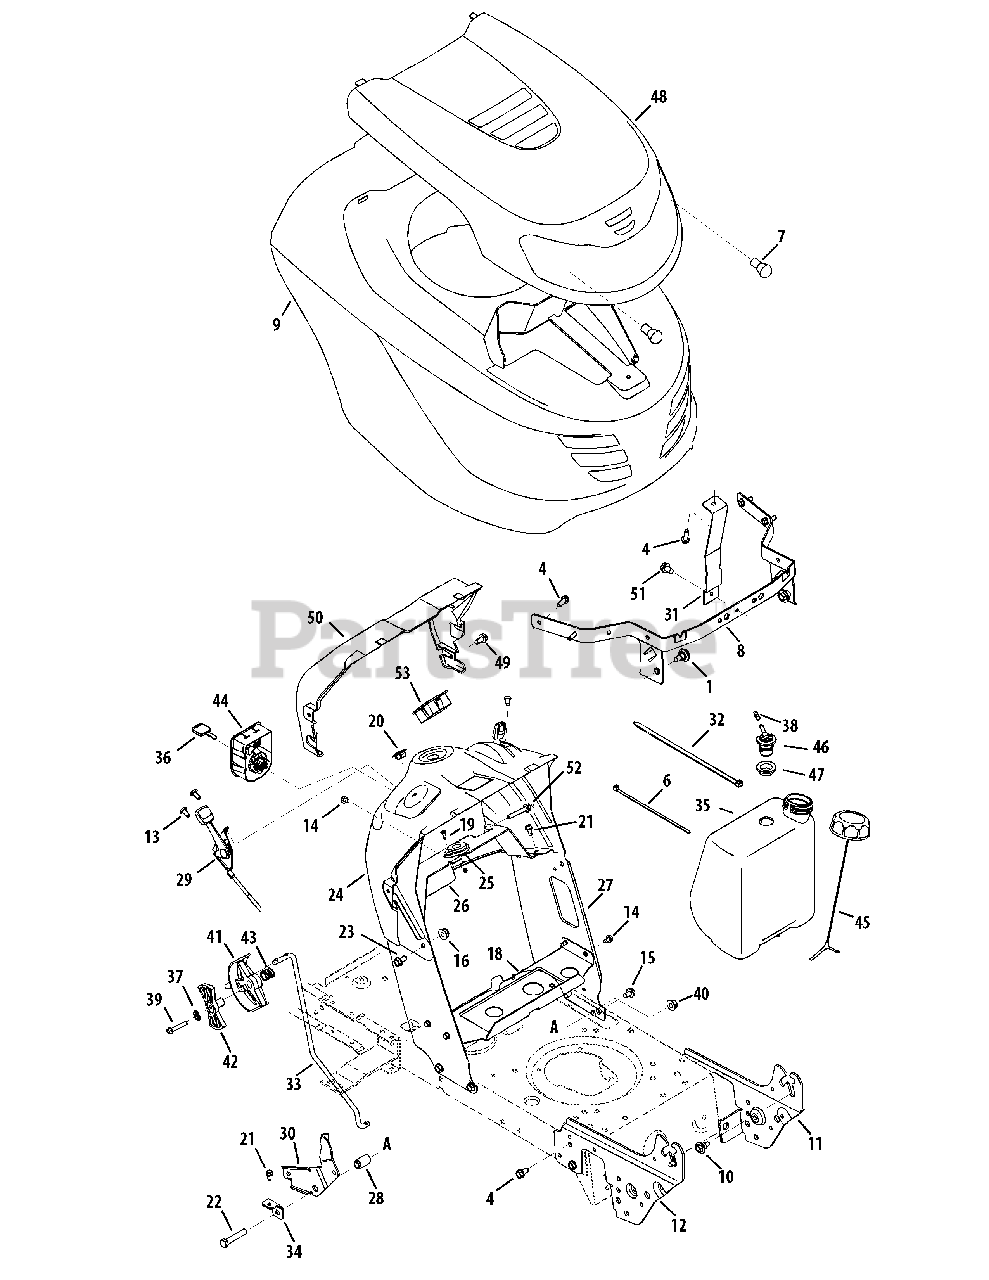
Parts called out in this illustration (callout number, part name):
1	Shoulder Screw 5/16-18, .43 x .29
4	Screw 5/16-18 x .75
6	Cable Tie 3/16 x 7.4
7	Miniature Lamp 12V Socket
8	Hood Pivot Bracket
10	Shoulder Screw 5/16-18 x .43 x .29
11	Left Support Pivot Bracket
12	Right Support Pivot Bracket
13	Self-Tapp Screw 1/4-20 x .50
14	Self-Tapp Screw 1/4-20 x .50
15	Screw 5/16-18 x .675
16	Flange Locknut 5/16-18 Gr. F, Nylon
18	Gas Tank Support Bracket
19	Screw, #10-16 x .50
20	Choke Plug
21	Tap Screw 1/4-20 x 0.625
22	Hex Screw 3/8-16 x 2.0 Gr. 5
23	Screw 5/16-18 x .625
24	Upper Dash
25	Bearing .628 ID x 1.36
26	Steering Support Bracket
27	Dash, Lower
28	Flange Spacer
29	Choke/Throttle Cable Ass’y (Sgl. Cyl.)
30	Speed Latch - No RMC
31	Hood Support Brkt.
32	Cable Tie
33	Speed Selector Control Rod
34	Speed Latch
35	Fuel Tank 1.36 gal.
37	Lockwasher 1/4ID
38	Hose Vent
39	Hex Washer Scr. 1/4-20 x 1.50
40	Hex L-Flg. Nut 3/8-16 Gr. F, Nylon
41	Shift Lever
42	Index Control
43	Compression Spring .685 OD x .63
44	3 Position Key Switch
45	Cap-Fuel
46	Rollover Valve
47	Rubber Grommet
48	Hood Scoop
49	Hi-Lo Screw 1/4-15 x .75
51	Hex Wash S-Tapp Scr 1/4-20 x .50
52	Hex Screw 1/4-20 x 1.5
53	Ammeter Plug
